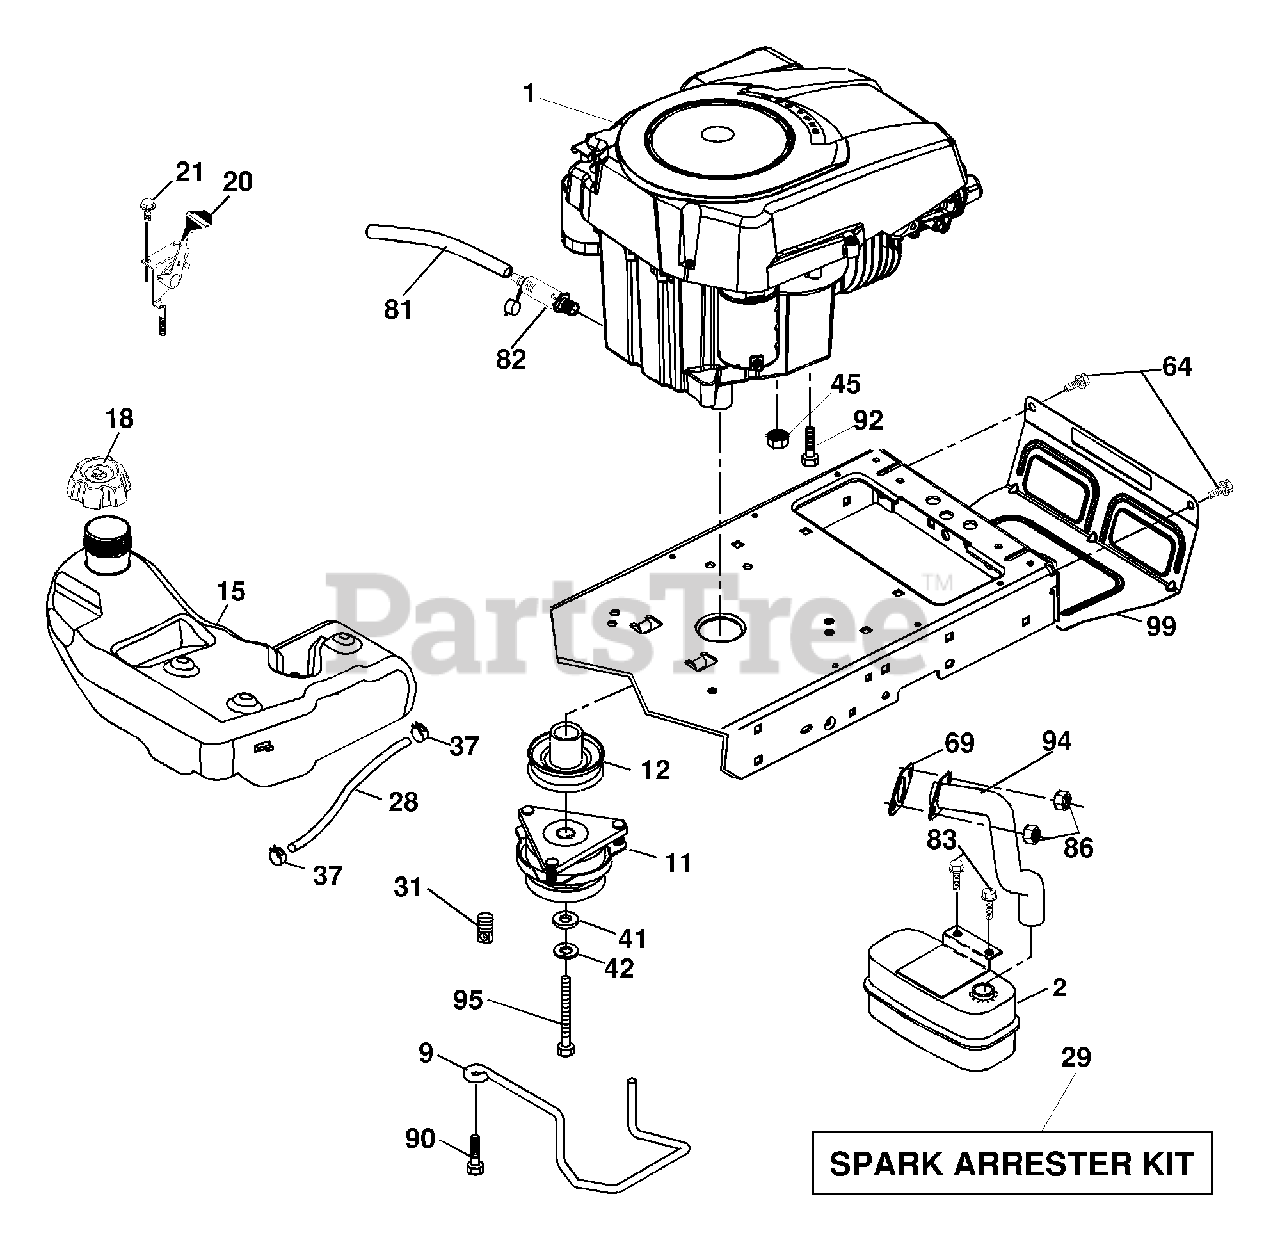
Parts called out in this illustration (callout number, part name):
9	Keeper Belt Engine
11	Clutch Ogura
12	Pulley Engine
15	Tank Fuel 4.0
18	Cap Asm
20	Control Throttle
21	Screw Thd Cut 1/4-20 x 1/2
28	Fuel Line
29	Spark Arrester Kit
31	Clip Push-In
37	Clamp Hose
41	Washer 1-1/2 OD x 15/32 ID x .250
42	Washer Lock 7/16
45	Nut Keps Hex 1/4-20 unc
64	Screw Hexwsh Thdrol 3/8-16 x 3/4
81	Tube Drain Oil Easy
82	Plug Drain Oil
83	Bolt 5/16-18 unc x 3/4 w/Sems
86	Nut Hex Flange Toplock M8-1.25
90	Screw 3/8-16 x 1
92	Screw 3/8-16 x 1
94	Tube Exhaust
95	Bolt Hex 7/16-20 x 4 Gr. 5
99	Shield Browning/Debris
